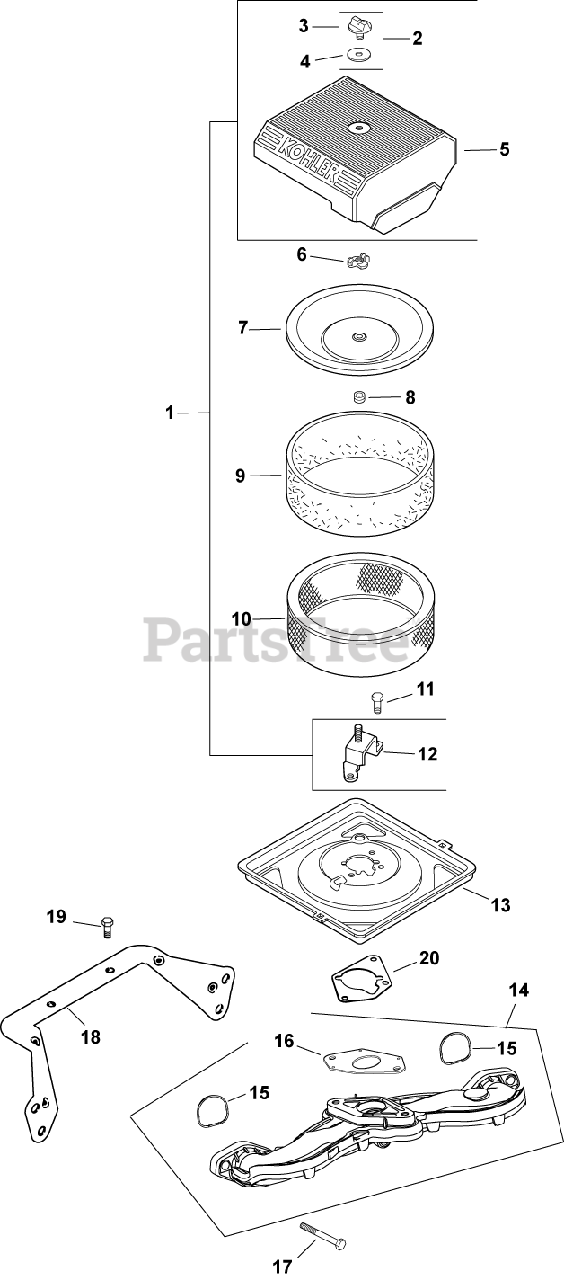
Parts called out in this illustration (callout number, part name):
1	KIT, AIR CLEANER COVER
2	KIT, KNOB W/SEAL
3	KNOB, COVER
5	COVER, AIR CLEANER
6	NUT, WING
7	COVER, INNER AIR CLEANER
8	SEAL, BREATHER
9	PRE-CLEANER (HIGH)
10	ELEMENT, AIR FILTER (HIGH) - Also available Retail Packaged 24 883 03-S1 Air Filter Kit
11	SCREW,FLG THD FRM M6X1.0X20-(#25086396S)
12	BRACKET, AIR CLEANER-USE 24 126 210-S
13	BASE, AIR CLEANER -USE 24 094 88-S
14	MANIFOLD, INTAKE - PLASTIC-USE 24 164 93
15	O-RING, INTAKE PORT
16	GASKET, CARBURETOR
17	SCREW, FLG M6X1.0X40
18	BRACKET, AIR CLEANER BASE
19	SCREW, FLG THD FRM M5X.8X10
20	GASKET, AIR CLEANER BASE
